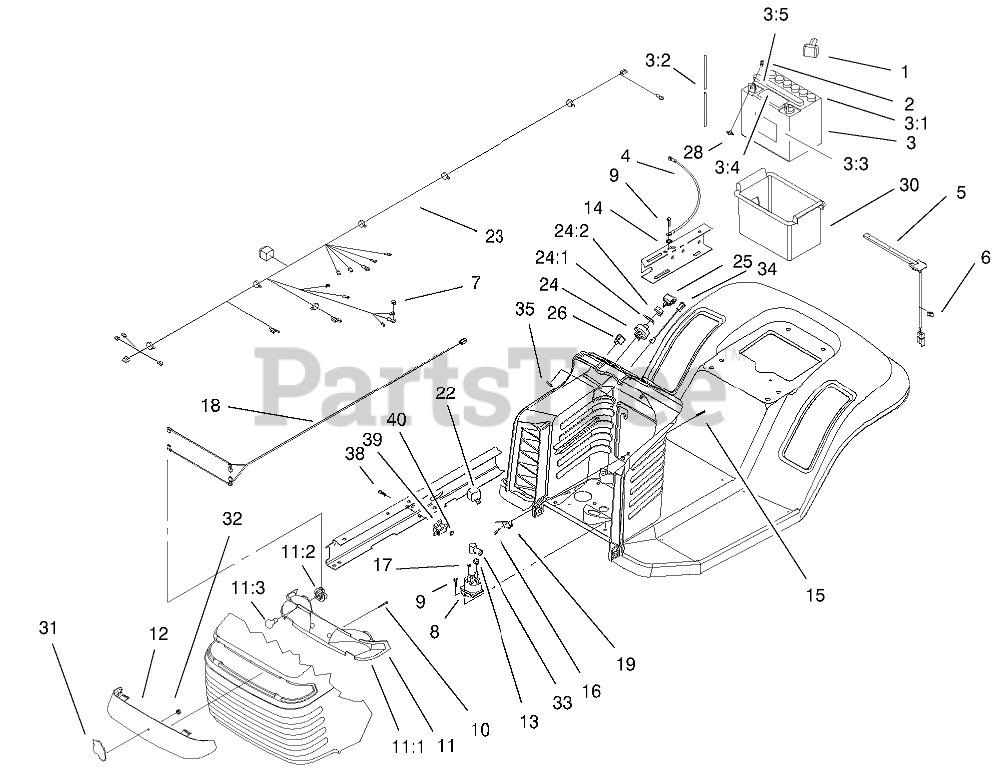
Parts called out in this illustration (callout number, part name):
1	BOOT-TERMINAL
2	SCREW-HH
3	Battery
3:1	CAP-BATTERY
3:2	TUBE-BATT DRAIN/80-2600
3:3	DECAL-BATTERY
3:4	DECAL-DANGER
3:5	DECAL - DANGER
4	WIRE ASM
5	SWITCH-SEAT
6	CLIP-RETAINER, WIRE
7	NUT-KEPS
8	SOLENOID
9	SCREW-HWH
11	HEADLIGHT REFLECTOR ASM
11:1	SOCKET-LIGHT
11:2	BULB
11:3	REFLECTOR-LIGHT
12	LENS-HEADLIGHT
13	NUT-KEPS
14	WASHER-LOCK/EXT
15	SCREW-HH
16	NUT-SPEED
17	NUT-KEPS
18	HARNESS-HEADLIGHT
19	SWITCH-MICRO
22	RELAY
23	HARNESS-WIRE
24	Key Switch ASM
24:1	WASHER-TOOTH, INTERNAL
24:2	NUT-HH
25	KEY-IGNITION
26	SWITCH-ROCKER
28	NUT-WING
30	BOX-BATTERY
31	EMBLEM-GRILLE WHEELHORSE
33	BOOT-TERMINAL INSULATOR
34	LIGHT-INDICATOR
35	CLIP-RETAINER
38	SCREW-HSH
39	SWITCH-POLE, SINGLE
40	NUT-LOCK, NI
